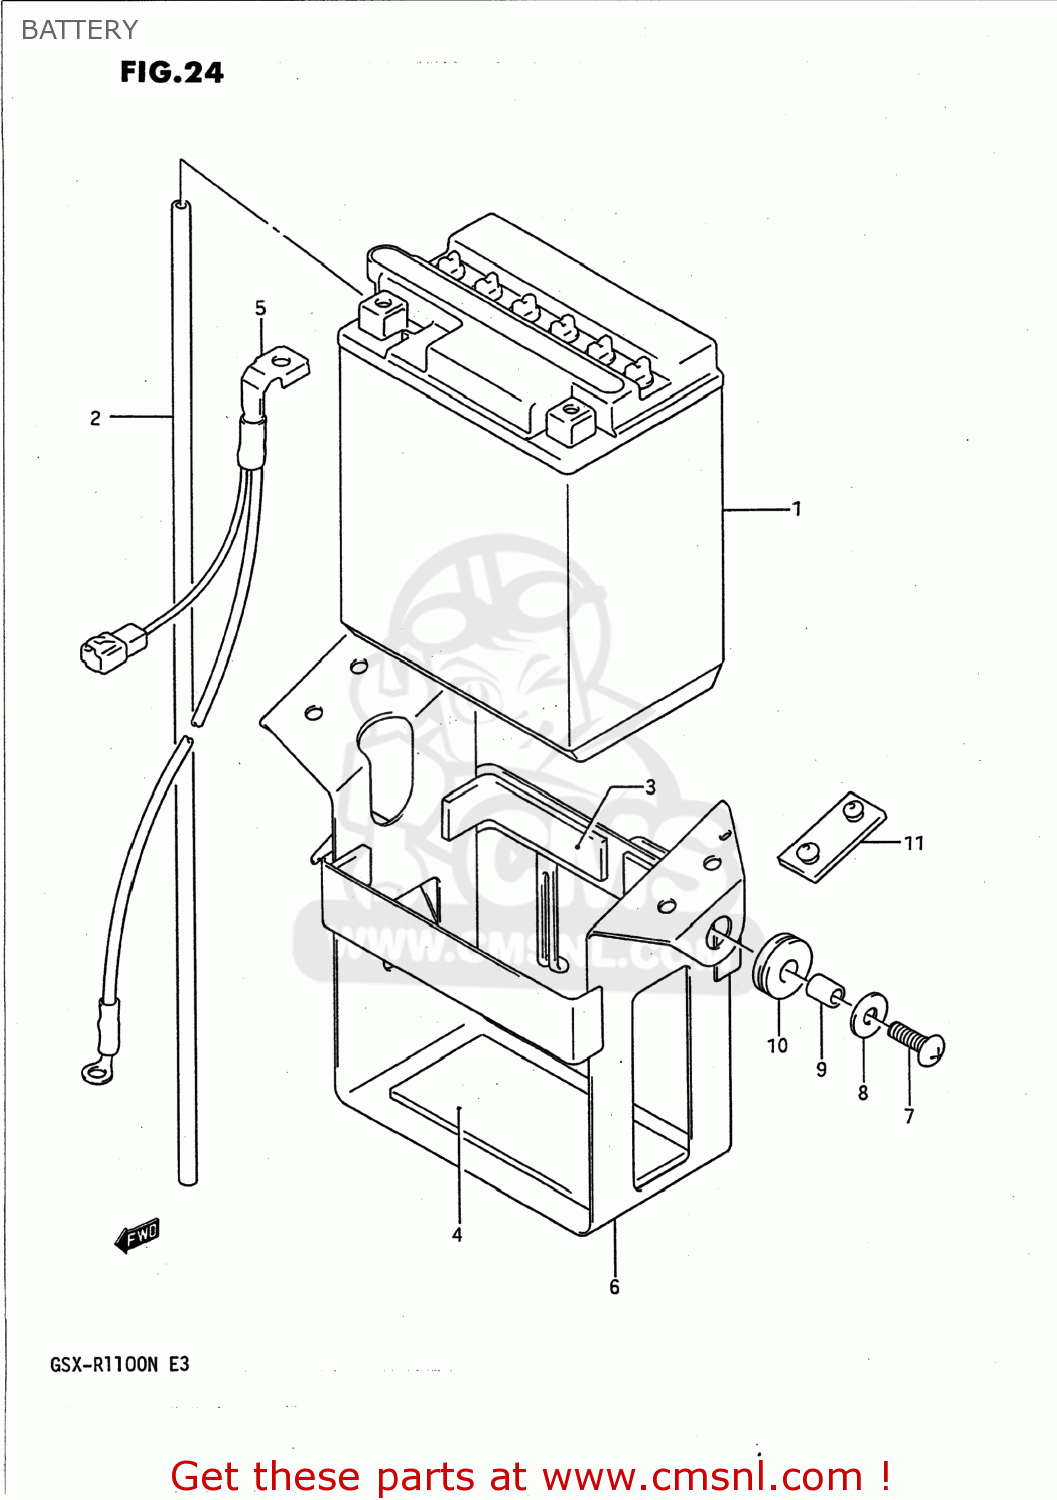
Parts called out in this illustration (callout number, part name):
1	BATTERY ASSY (12V)
2	HOSE,BATTERY EXHAUST
3	PROTECTOR,20X9
4	PROTECTOR(170X95X3.0)
5	WIRE,BATTERY MINUS LEAD
6	HOLDER COMP,BATTERY
7	SCREW
8	WASHER
9	SPACER
10	CUSHION
11	CUSHION
